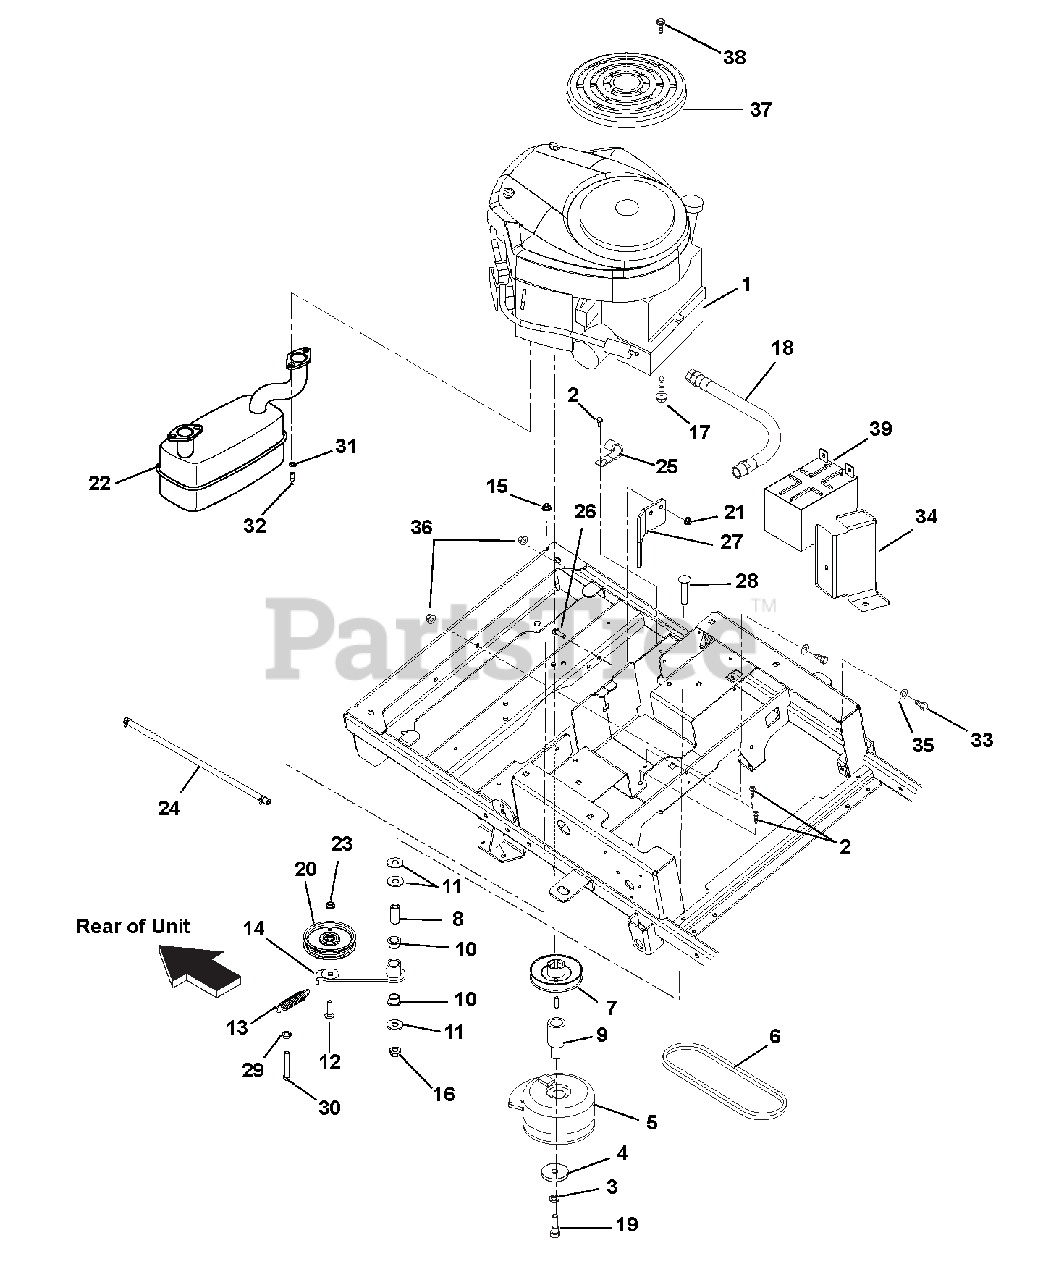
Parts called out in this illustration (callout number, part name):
1	ENGINE, 18HP V-TWIN CE
2	@SCR-TAP .25-20X.37 HWH YWZ TR
3	@WSHR-LK .44X.109 REG YWZC
4	WSHR-FL-STL .469X2.00X.25 YWZC
5	CLUTCH, MS WITH BRAKE
6	V-BELT, HA-WRAPPED
7	PLY-V 4.5X1.5 AB SECTION W/KEY
8	BSHG-SLV .500X.750X1.560
9	EXT-CRANKSHAFT LOWER
10	BSHG-FLG 0.75X0.875X.625X1.125
11	@WSHR-FL-STL.563X1.38X.109YWZC
12	@BLT-RDHDSQNK .38-16X1.50 G5YZ
13	SG-TENS .105X.812X3.88 WLD 15
14	WMT, GROUND DRIVE IDLER ARM
15	@NUT-LK-NYL-FLG .38-16 YWZC
16	@NUT-LK-TOP-FLG .50-13 YWZC
17	@SCR-TAP .38-16X1.00 HWH TR YZ
18	HOSE, HYD .38-11-0K M6N0-F6J0
19	BLT-HEX .44-20X4.50 GR8 YWZC
20	ASM, 4" IDLER (.75 WIDE)
21	@NUT-LK-NYL-FLG .31-18 YWZC
22	MUFFLER - TWIN BRIGGS
23	@NUT-LK-TOP-FLG .38-16 YWZC
24	HOSE, FUEL(CARB APPROVED)
25	J-CLAMP
26	@BLT-HEX .31-18X1.00 GR5 YWZC
27	CLUTCH STOP
28	@BLT-RDHDSQNK .50-13X2.50 G5YZ
29	@NUT-SPNLK-FLG .375-16 YWZC
30	@BLT-HEX .38-16X2.50 GR5 YWZC
31	@WSHR-LK .31X.078 REG YWZC
32	SCR-CAP .31-18X.75 S/HD
33	@BLT-HEX .25-20X.75 GR5 YWZC
34	BRKT, BATTERY HOLD DOWN
35	@WSHR-FL-STL.281X.62X.065 YWZC
36	NUT-KEPS .250-20
37	GUARD, BRIGGS ENGINE
38	SCREW, 8-16X.87 PHPAN 3 LOBE
39	BATTERY, 12V; 215 CCA GEP
40	CLAMP, FUEL LINE
